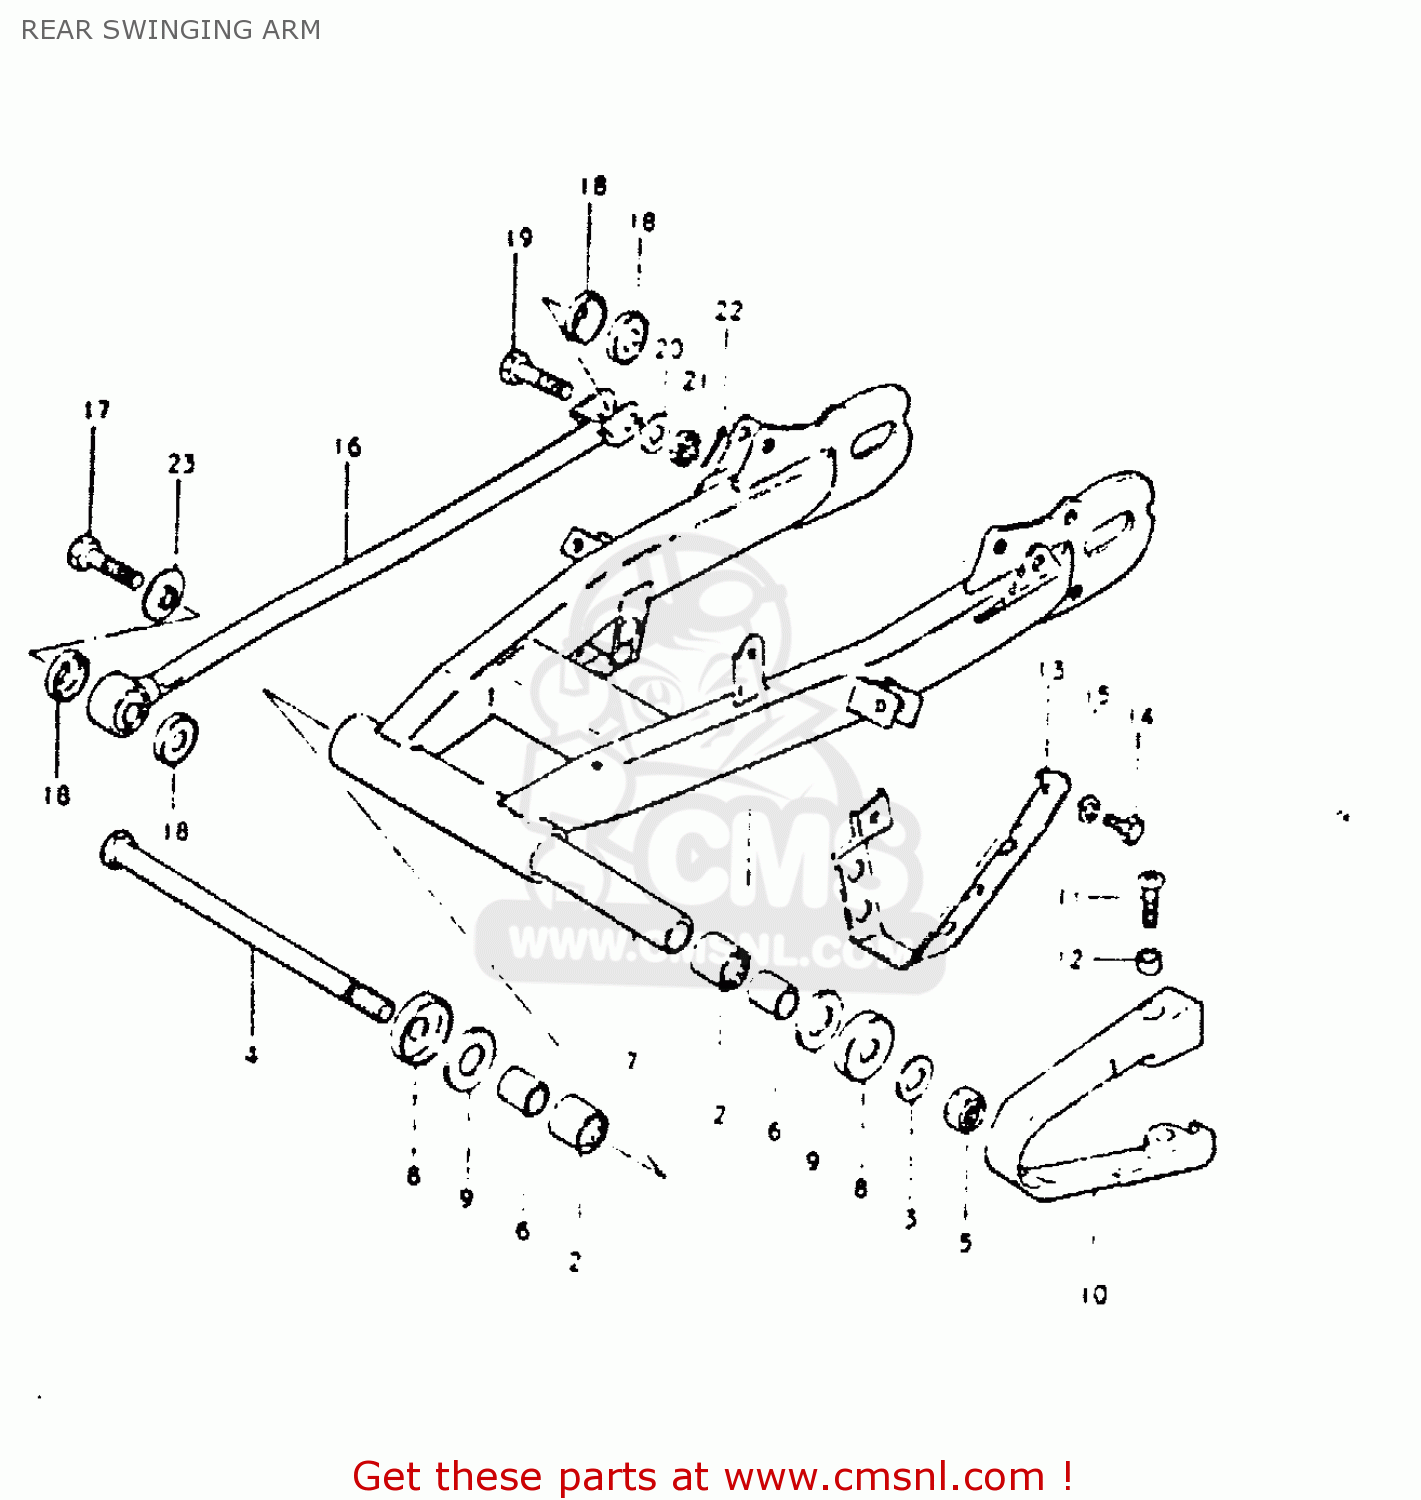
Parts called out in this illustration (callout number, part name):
1	REAR SWINGING ARM
2	BEARING(22X29X20)
3	WASHER
4	SHAFT,REAR SWING ARM
5	NUT 16MM
6	SPACER,RR SWGARM PIVOT
7	SPACER (16.2X21.7X142)
8	COVER,RR SWGARM DUST SEAL
9	WASHER
10	BUFFER,CHAIN TOUCH DEFLECTOR
11	SCREW,CHAIN TOUCH DEFEND
12	SPACER (5.5X8X4)
13	GUIDE,CHAIN
14	BOLT 8X12
15	LOCK WASHER
16	TORQUE LINK,REAR
17	BOLT(8X25)
18	19
19	BOLT 8X28
20	WASHER
21	NUT 8MM
22	PIN 20X20
23	WASHER
